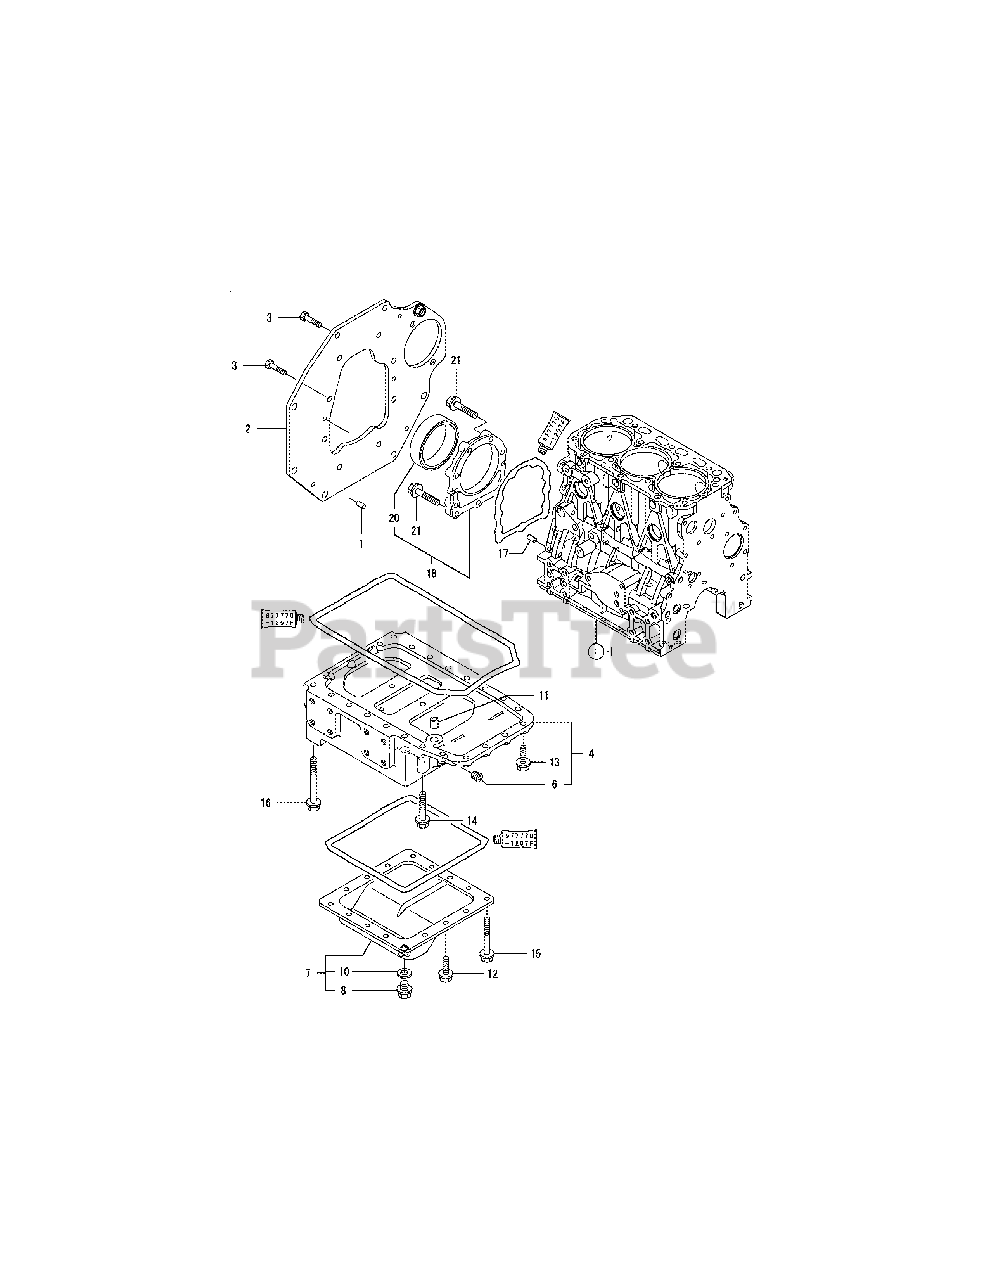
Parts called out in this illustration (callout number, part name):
2	FLANGE, MOUNTING
4	SUMP ASSY, LUB.OIL
7	COVER, OIL PAN
8	PLUG, DRAIN 12
10	WASHER, SEAL 12
11	PIPE, KNOCK 14X19
18	CASE ASSY, OIL SEAL
